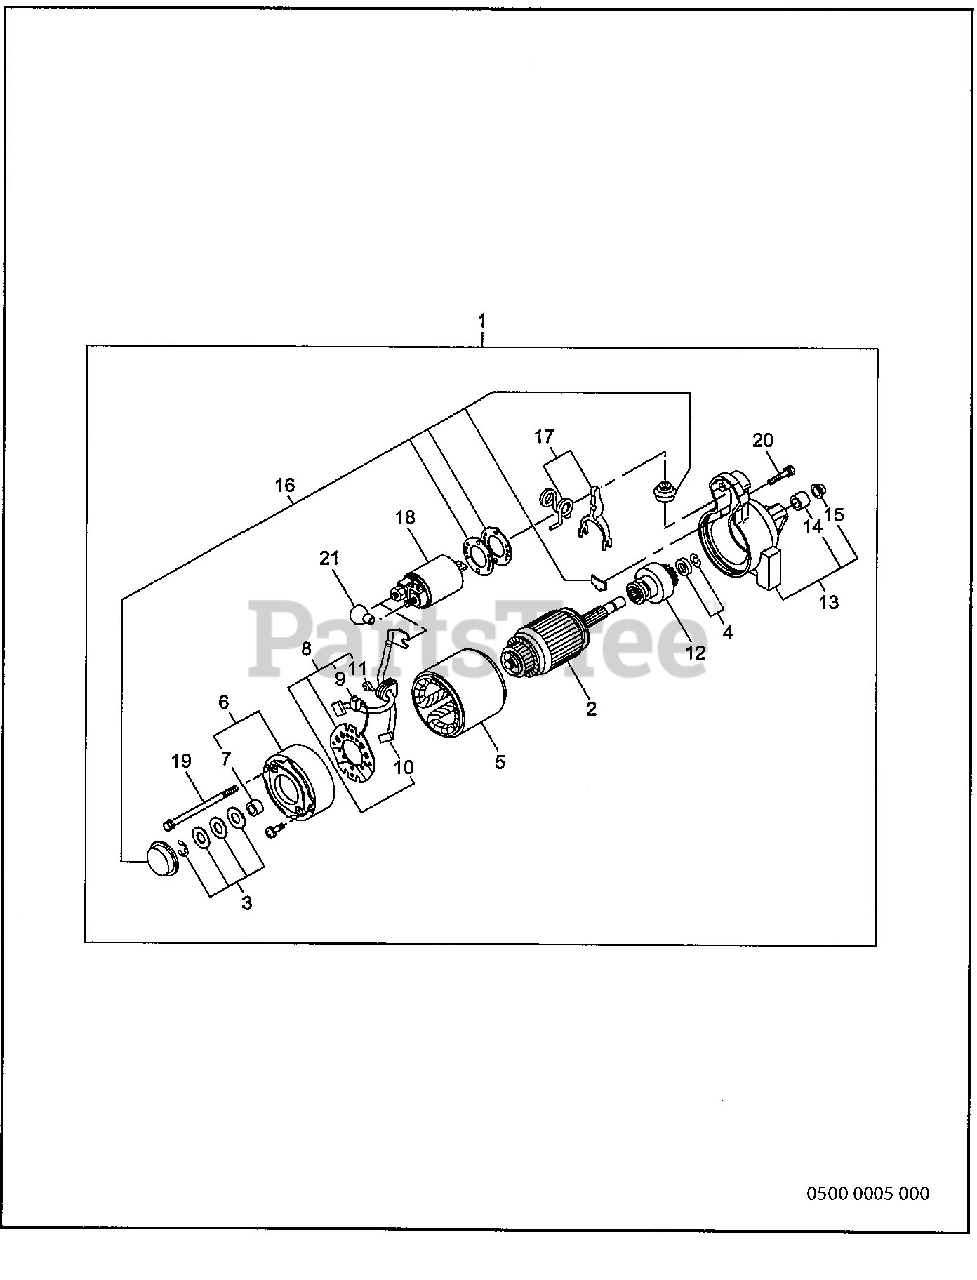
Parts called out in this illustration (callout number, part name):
1	STARTING MOTOR ASSY
3	THRUST WASHER KIT
4	PINION STOPPER SET
6	REAR COVER ASSY
8	BRUSH HOLDER ASSY
13	GEAR CASE ASSY
16	DUST COVER KIT
17	SHIFT LEVER KIT
18	MAGNETIC SWITCH ASSY
